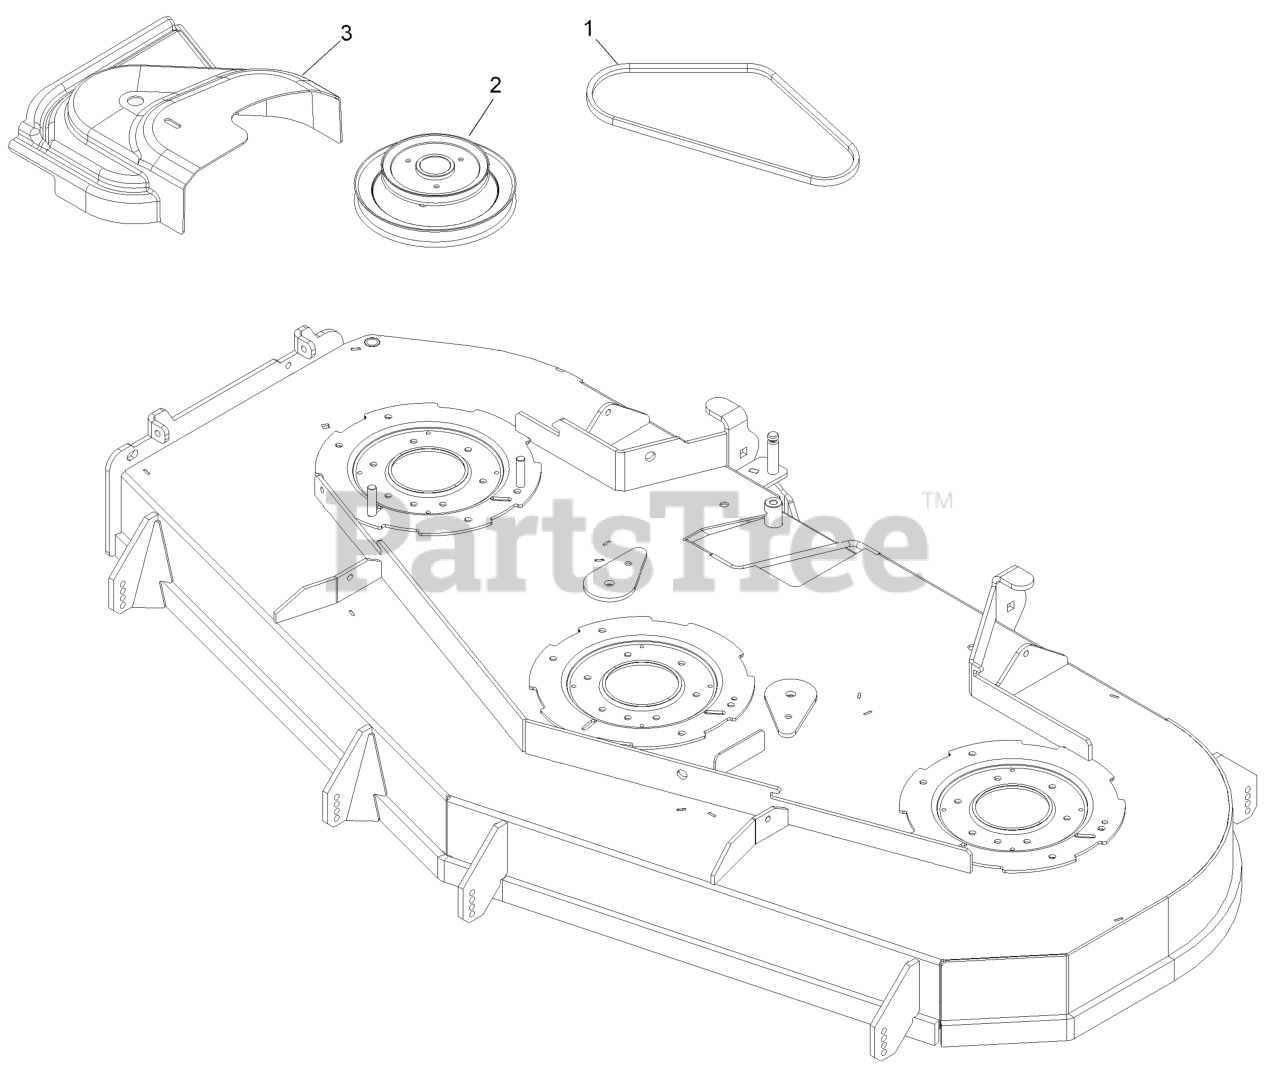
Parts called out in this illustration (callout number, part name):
1	BELT, BLOWER DRIVE 72
2	JACKSHAFT,UV DRIVE 724 SPLINED
3	COVER,BELT UV 72
